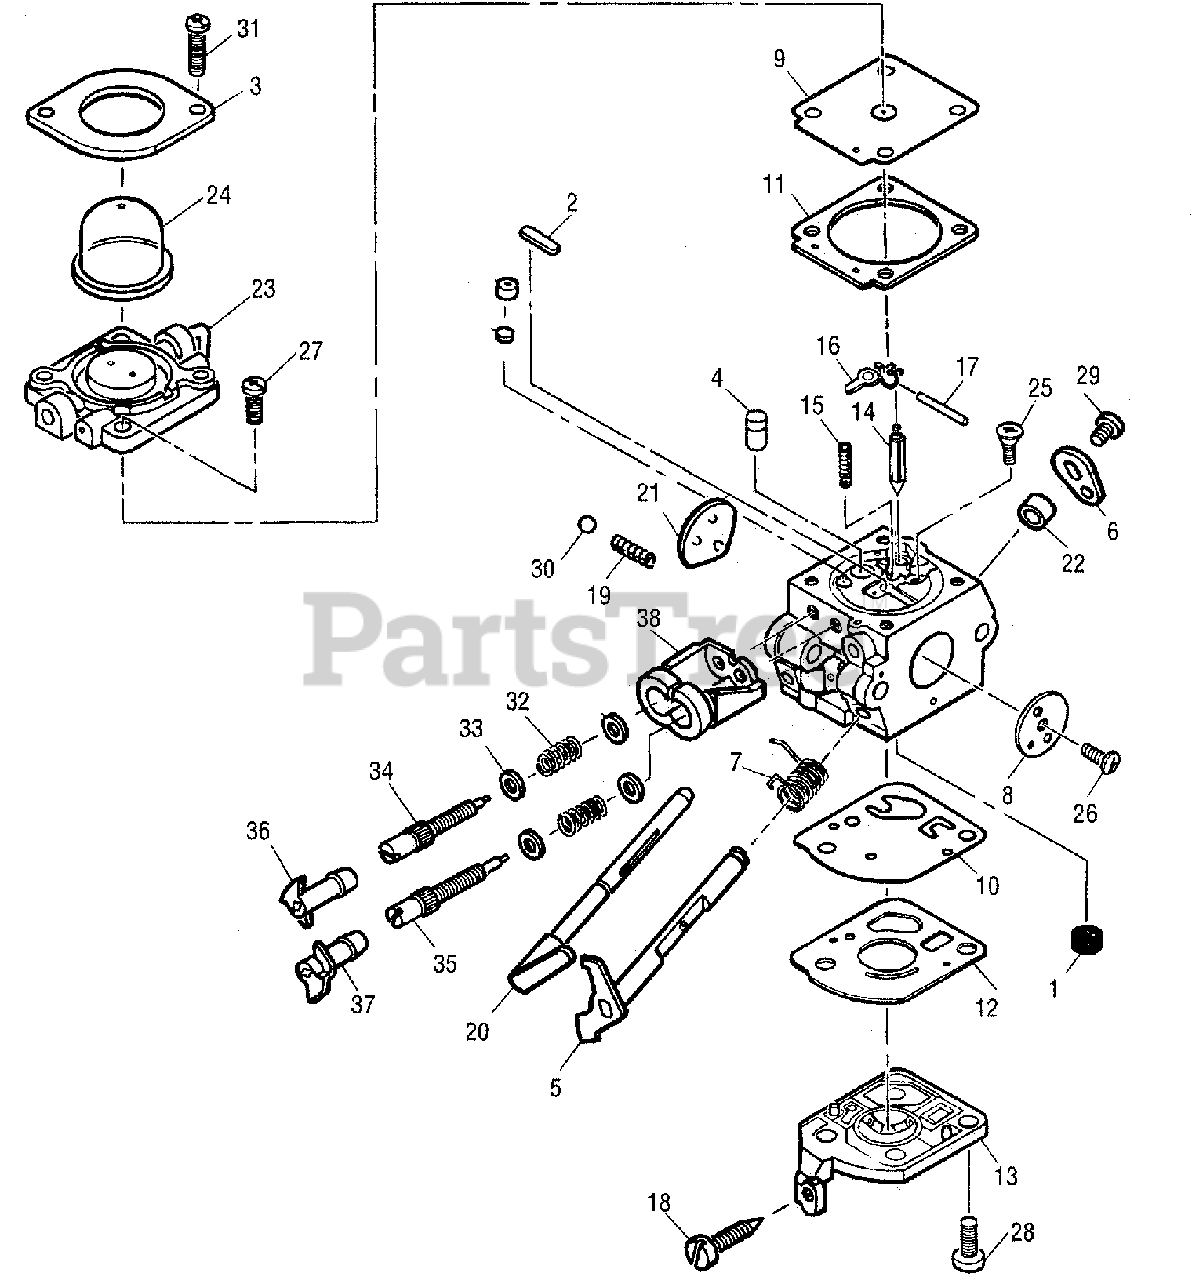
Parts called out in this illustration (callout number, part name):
1	Strainer
2	Plug, Welch
3	Retainer, Prime
4	Nozzle Asy, Check Valve
5	Shaft Asy, Throttle
6	Lever, Throttle
7	Spring, Throttle Return
8	Valve, Throttle
9	Diaphragm Asy, Metering
10	Diaphragm, Pump
11	Gasket, Metering Chamber
12	Gasket, Pump
13	Cover, Pump
14	Valve, Inlet Needle
15	Spring, Metering Lever
16	Lever, Metering
17	Pin
18	Screw, Throttle Adjust
19	Spring, Friction
20	Shaft Asy, Choke
21	Valve, Choke
22	Collar
23	Base Asy, Primer
24A	Primer Bulb
25	Screw, Pin
26	Screw, Throttle Valve
27	Screw, Metering Cover
28	Screw, Pump Cover
29	Screw, Throttle Lever
30	Ball, Steel
31	Screw, Retainer
32	Spring, Adjust Screw
33	Washer, Limiter
34	Screw, Hi Speed
35	Screw, Low Speed
36	Limiter Cap, High
37	Limiter Cap, Low
38	Retainer, Limiter
